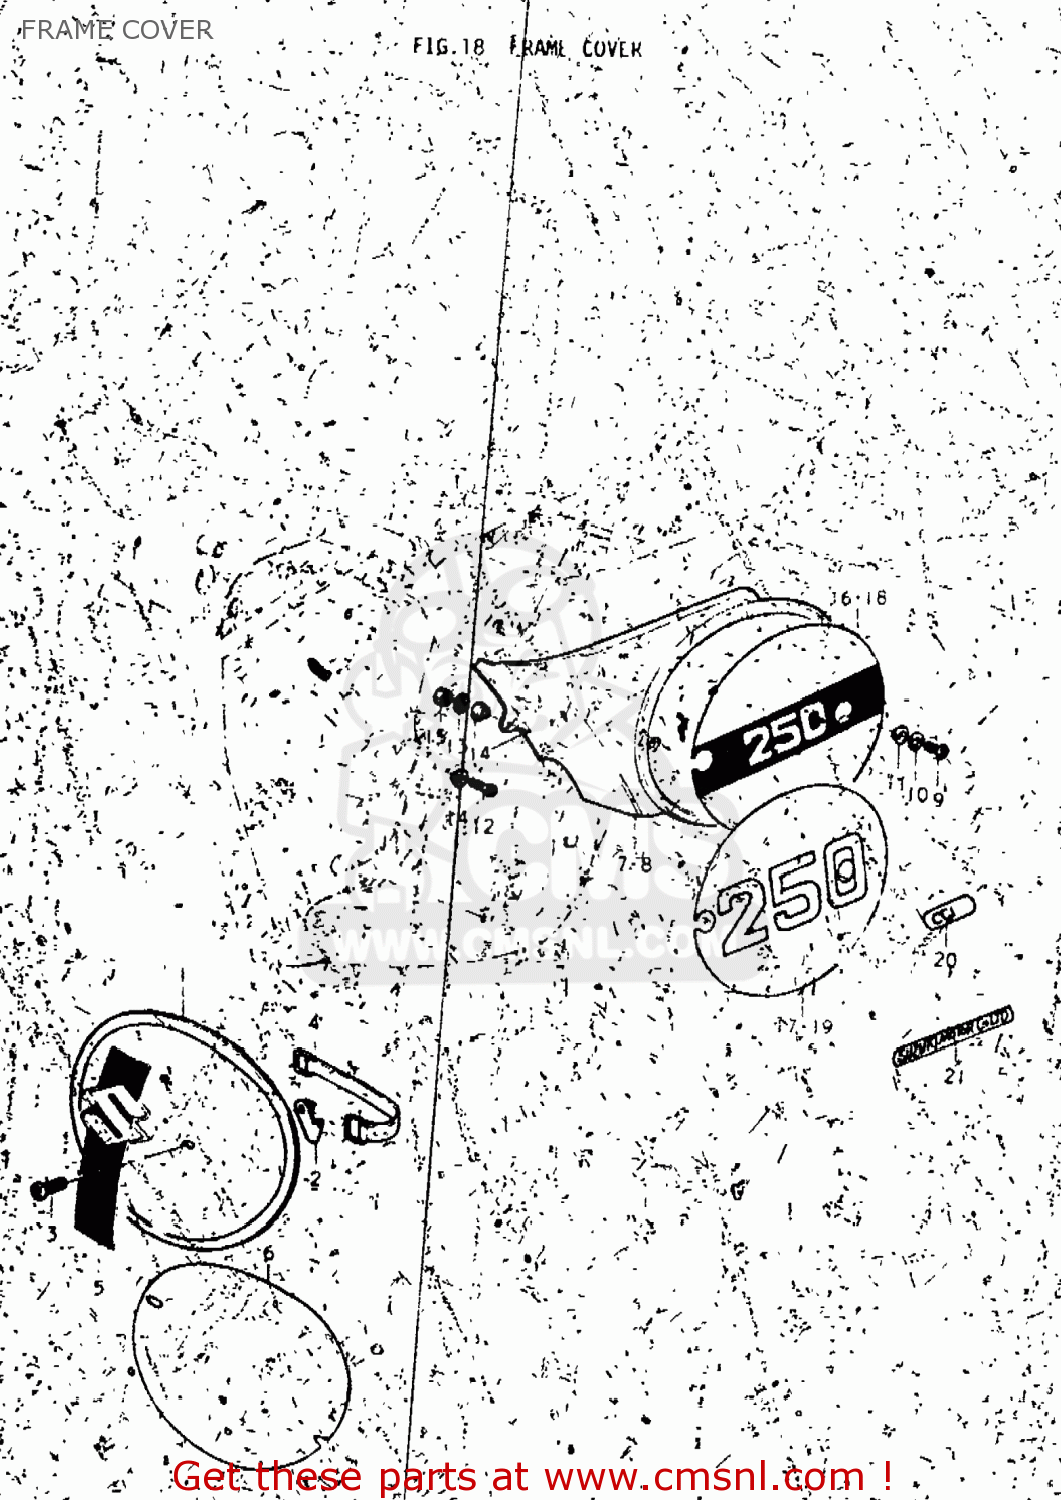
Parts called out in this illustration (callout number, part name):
1	PLATE SET,FRONT
3	SCREW 6X12
4	BAND
5	EMBLEM,FRONT NUMBER PLATE
6	EMBLEM,FRONT NUMBER PLATE
7	COVER,FRAME,RIGHT
8	COVER,FRAME,LEFT
9	SCREW 6X12
10	LOCK WASHER
11	WASHER
12	SCREW
13	LOCK WASHER
14	WASHER
16	EMBLEM
17	EMBLEM
18	EMBLEM,FRAME COVER
19	EMBLEM,FRAME COVER
20	EMBLEM,CCIS
21	LABEL,COMPANY NAME
